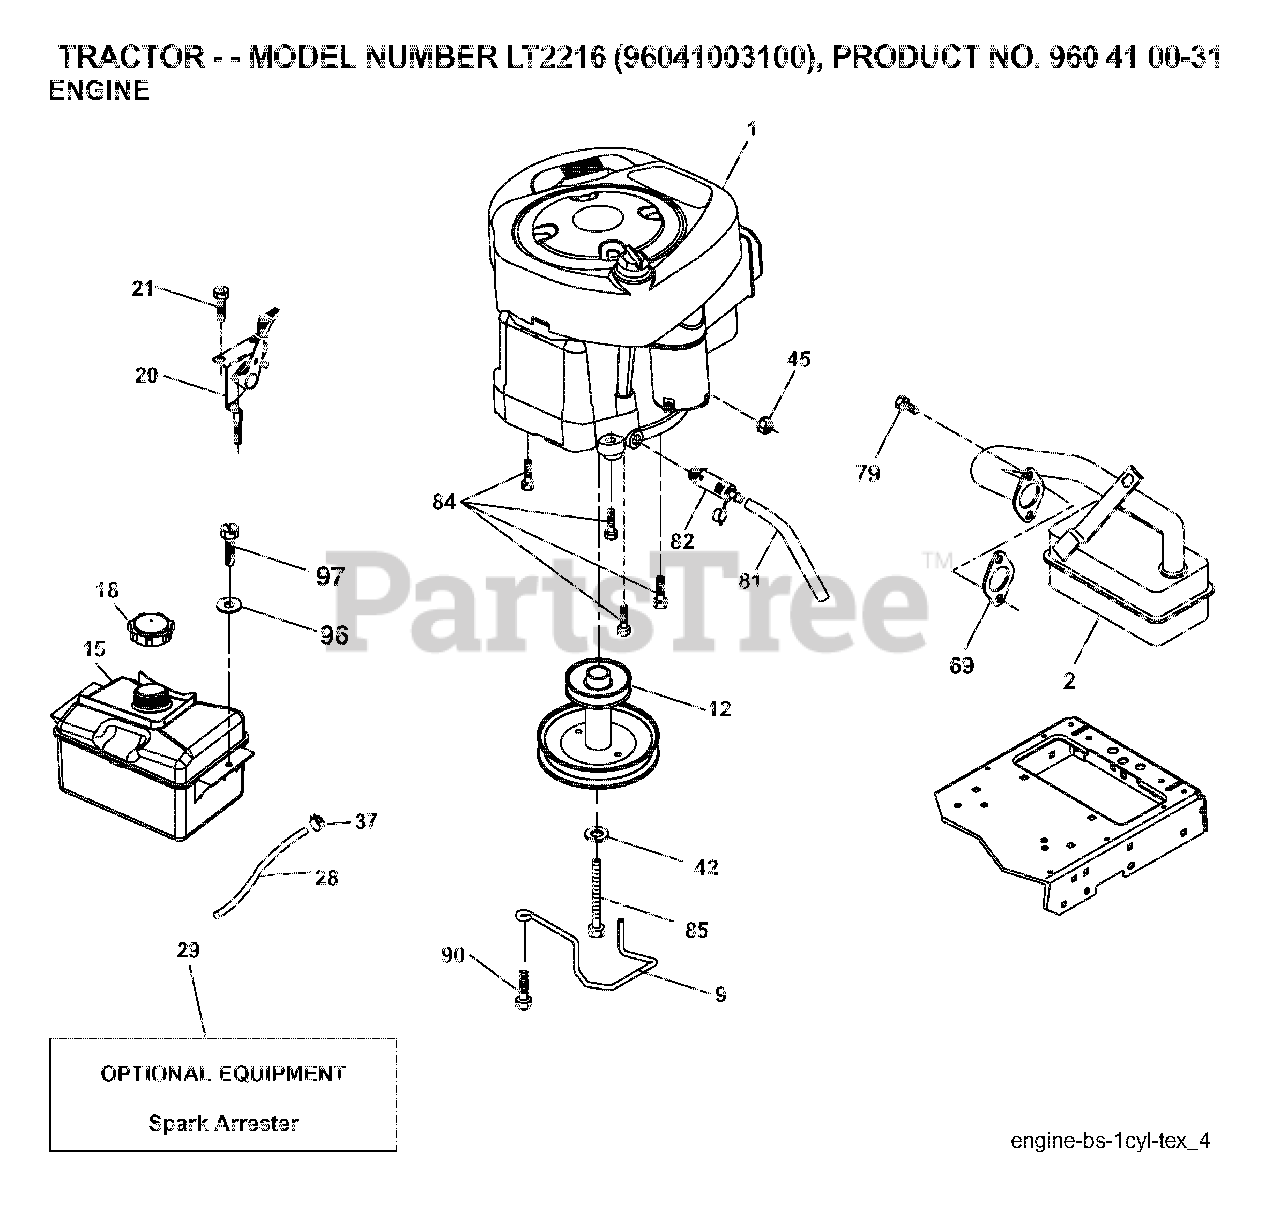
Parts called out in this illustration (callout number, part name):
9	KEEPER.BELT.ENGINE.3.25
12	PULLEY ENGINE
15	TANK FUEL FRT 1.5 GAL
18	FUEL CAP
20	CONTROL.TH/CK.C.
21	SCREW
28	LINE.FUEL.20
29	ARRESTER SPARK (OPTIONAL)
37	HOSE CLAMP
42	LOCKWASHER
45	NUT
69	REPL BY 532 27 22-93
79	SCREW.SOCKET HD.5/16-1
81	TUBE, DRAIN OIL ASM.
82	PLUG DRAIN OIL EASY
84	SCREW.3/8-16
85	BOLT HEX 7/16-20X4-1/4"
90	SCREW 3/8-16X1
97	SCREW HEXWSHR 1/4-20X3/4
